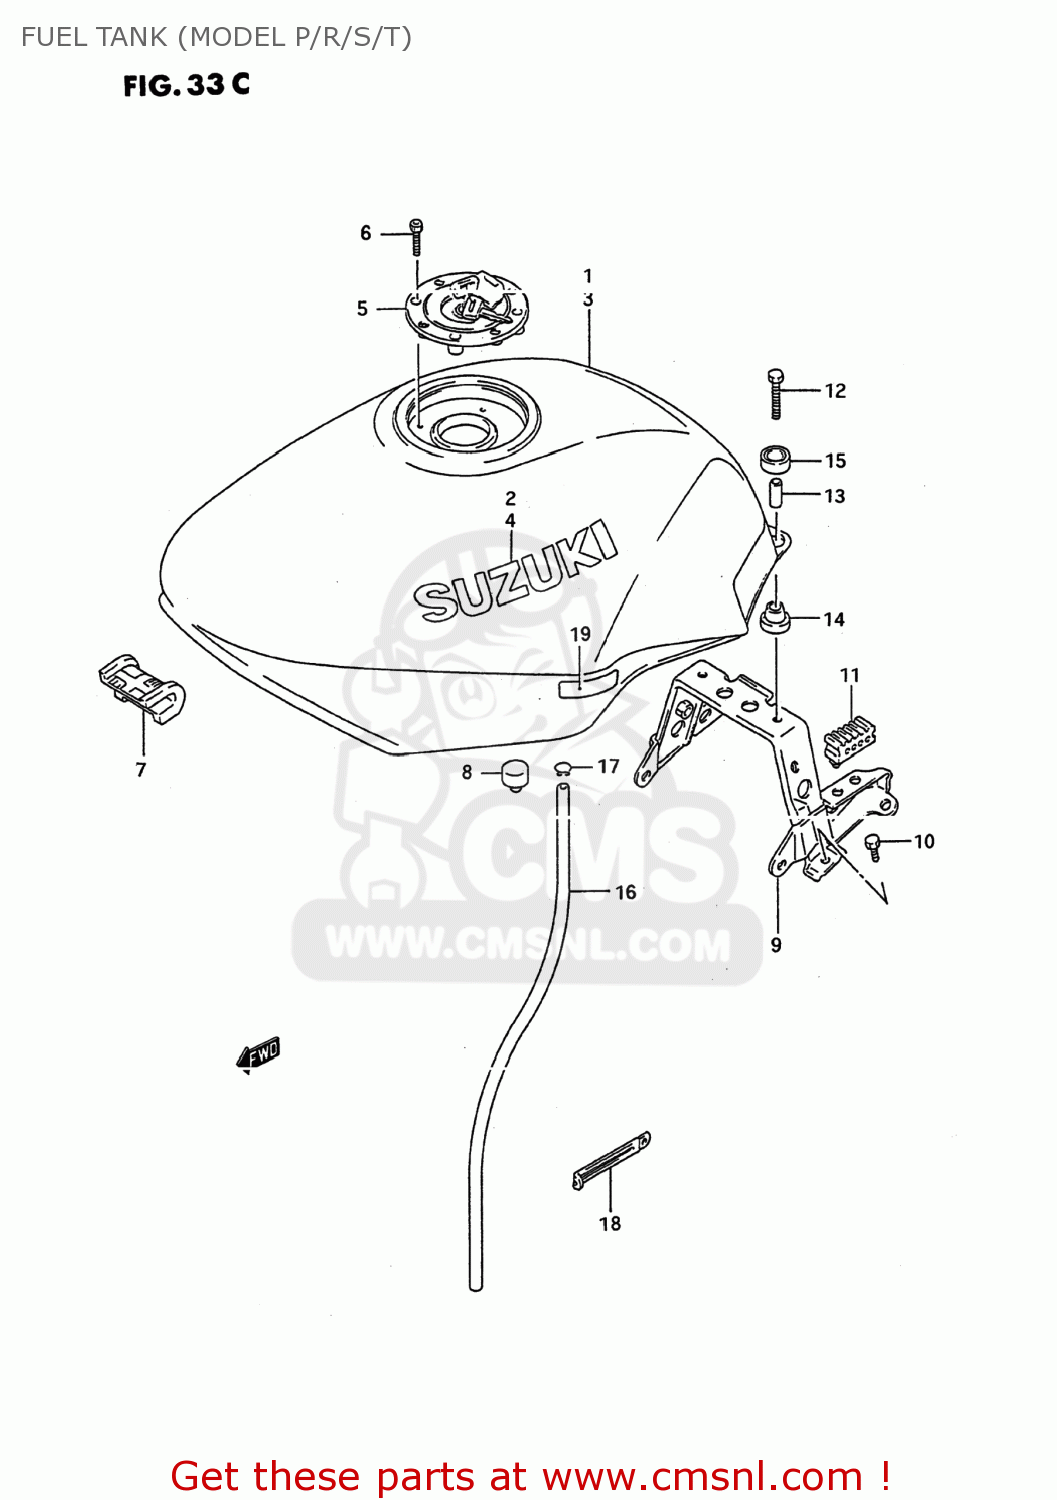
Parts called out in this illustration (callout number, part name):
1	TANK ASSEMBLY,FUEL
2	EMBLEM,FUEL TANK
3	TANK ASSEMBLY,FUEL
4	EMBLEM,FUEL TANK
5	CAP SET,FUEL TANK
6	BOLT(5X20)
7	CUSHION,FUEL TANK FR
8	CUSHION
9	BRACKET,FUEL TANK RR
10	SCREW
11	CUSHION,SEAT(40X20X15)
12	BOLT
13	SPACER
14	CUSHION
15	CUSHION
16	HOSE,FUEL TANK WATER DRAIN
17	CLIP
18	CLAMP(L:120 T:1.0)
19	PROTECTOR(12X40)
